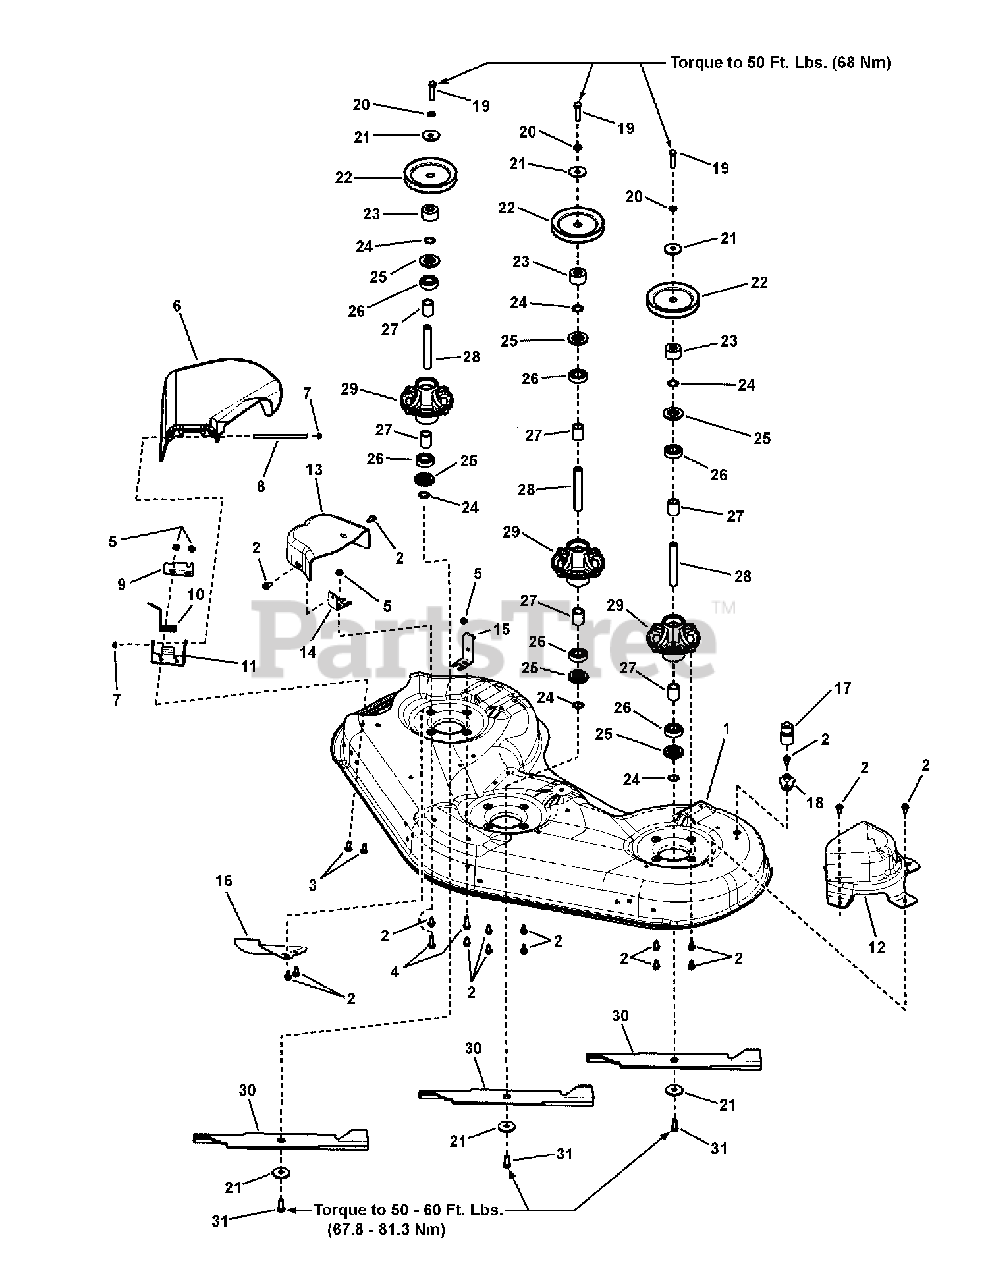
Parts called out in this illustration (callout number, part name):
1	HOUSING, 52" Mower, Snapper Red
2	SCREW, 5/16-18 x 3/4" Hex Washer Taptite
3	BOLT, 5/16-18 x 7/8" Round Head Short Square Neck Carriage, GR5
4	SCREW, 5/16-18 x 1-1/4" Hex Washer Self-Tap
5	NUT, 5/16-18 Hex Flange Lock, Small - Black
6	DEFLECTOR, Discharge
7	PUSH NUT, 5/16"
8	ROD, Deflector
9	PLATE, Deflector Closeoff
10	SPRING, Torsion Deflector
11	HINGE, Deflector, 52"
12	BELT COVER, 52" Mower, LH
13	BELT COVER, 52" Mower, RH
14	BRACKET, Belt Cover, Front
15	BRACKET, Belt Cover, Rear
16	BAFFLE, Pinchoff
17	CONNECTOR, Washout Port
18	ADAPTER, Washout Port, 52" Deck
19	SCREW, 7/16-14 x 1-3/4" Hex Head Cap, GR5
20	LOCKWASHER, Spring, .438
21	WASHER, Spring
22	PULLEY, 5.5 OD x 11 Ga. Split
23	SPACER, Pulley, Powdered Metal
24	RING, Self-Locking
25	SHIELD, Arbor, 2"
26	BALL BEARING, 20mm
27	SPACER, Bearing, Powder Metal
28	SHAFT, Spindle, 20mm
29	HOUSING, Arbor Bottom w/Lube Fitting
30	BLADE, Mower
31	SCREW, 7/16-14 x 1" Hex Head Cap, GR5
